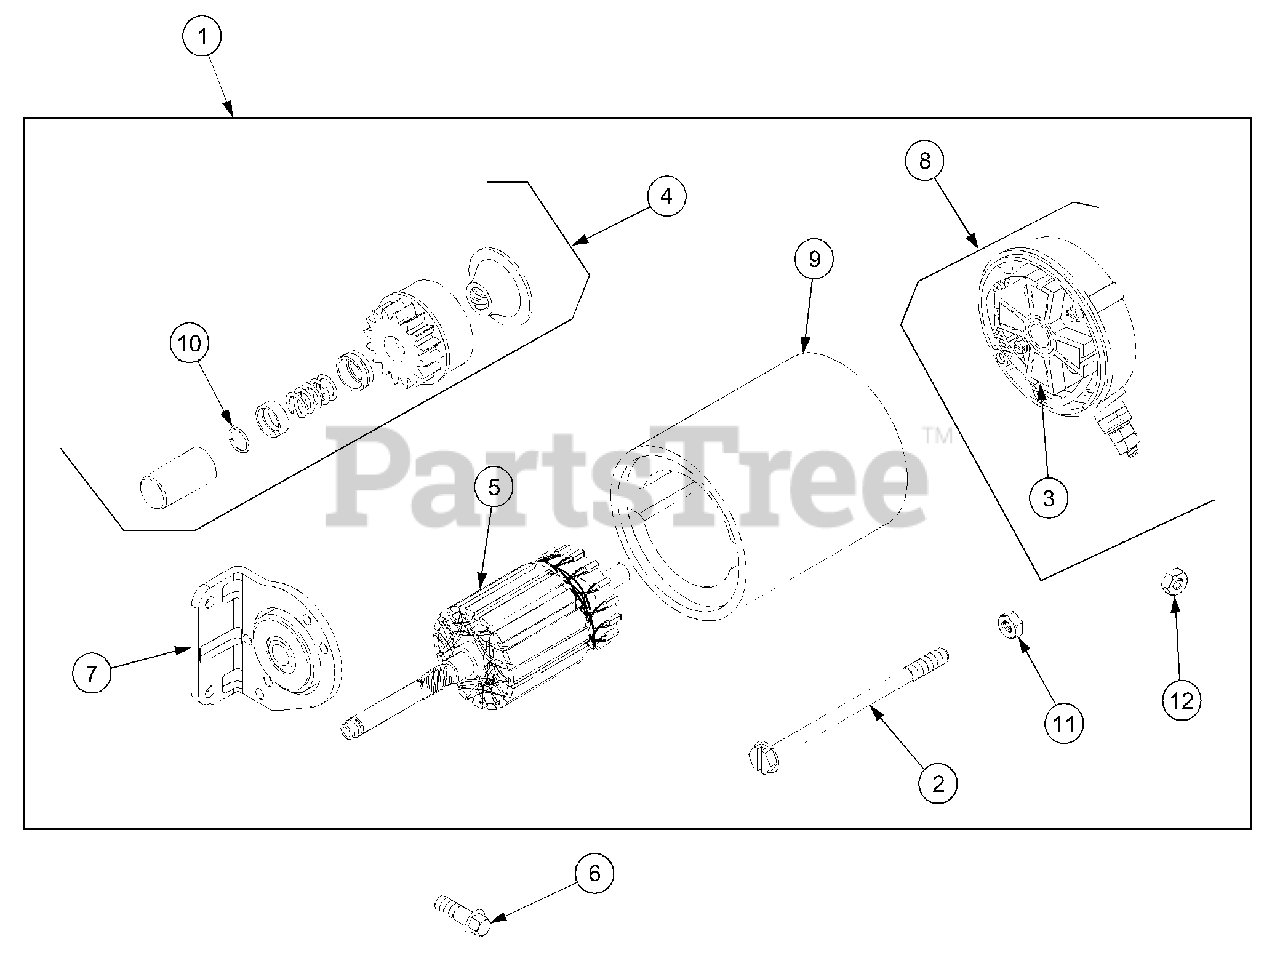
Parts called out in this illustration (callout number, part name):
1	Starter Motor Assembly
2	Bolt, Starter Motor
4	Drive, Starter
5	Armature Assembly
6	Screw, Drive Cap
9	Housing, Starter
10	Ring, Retaining
11	Nut, Starter Motor
12	Nut, Brush Retainer
